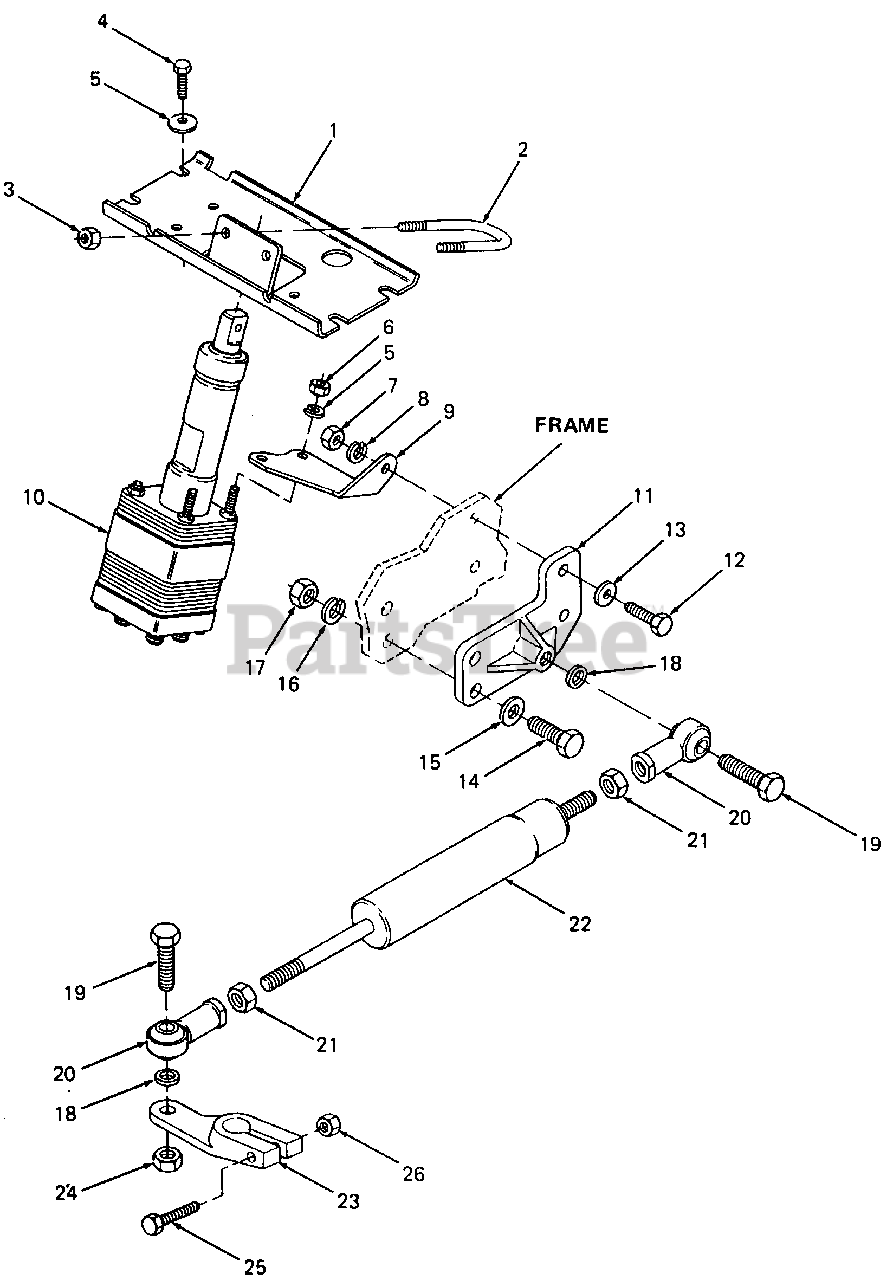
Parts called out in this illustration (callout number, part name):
1	Plate, Steering Support
3	Nut, Hex Center Lock, 5/16-24
4	Screw, Hex Cutting, 5/16-18 X .75 Lg
5	Washer, Bell, .345 X .88 X .060 Thk
6	Nut, Hex, 5/16-24 GR5
7	Nut, Hex Center Lock, 3/8-16 GR5
8	Washer, Lock, 3/8
9	Bracket, Power Steering Box Mtg
10	Power Steering Box w/Flat
13	Washer, Flat, .385 X .87 X .06 Thk HDN
14	Screw, Hex Cap, 1/2-13 X 1.25 Lg GR5
15	Washer, Flat, .51 X 1.12 X .06 Thk HDN
16	Washer, Lock, 1/2
17	Nut, Hex Center Lock, 1/2-13 GR5
18	Washer, Flat, .531 X .688 X .054 Thk
19	Screw, Hex Cap, 1/2-20 X 1.5 Lg GR5
20	Alignaball End, 1/2-20
21	Nut, Hex Jam, 1/2-20 GR5
24	Nut, Hex, 1/2-20 GR5
25	Screw, Hex Cap, 5/16-18 X 1.38 Lg GR5
26	Nut, Hex Center Lock, 5/16-18 GR5
